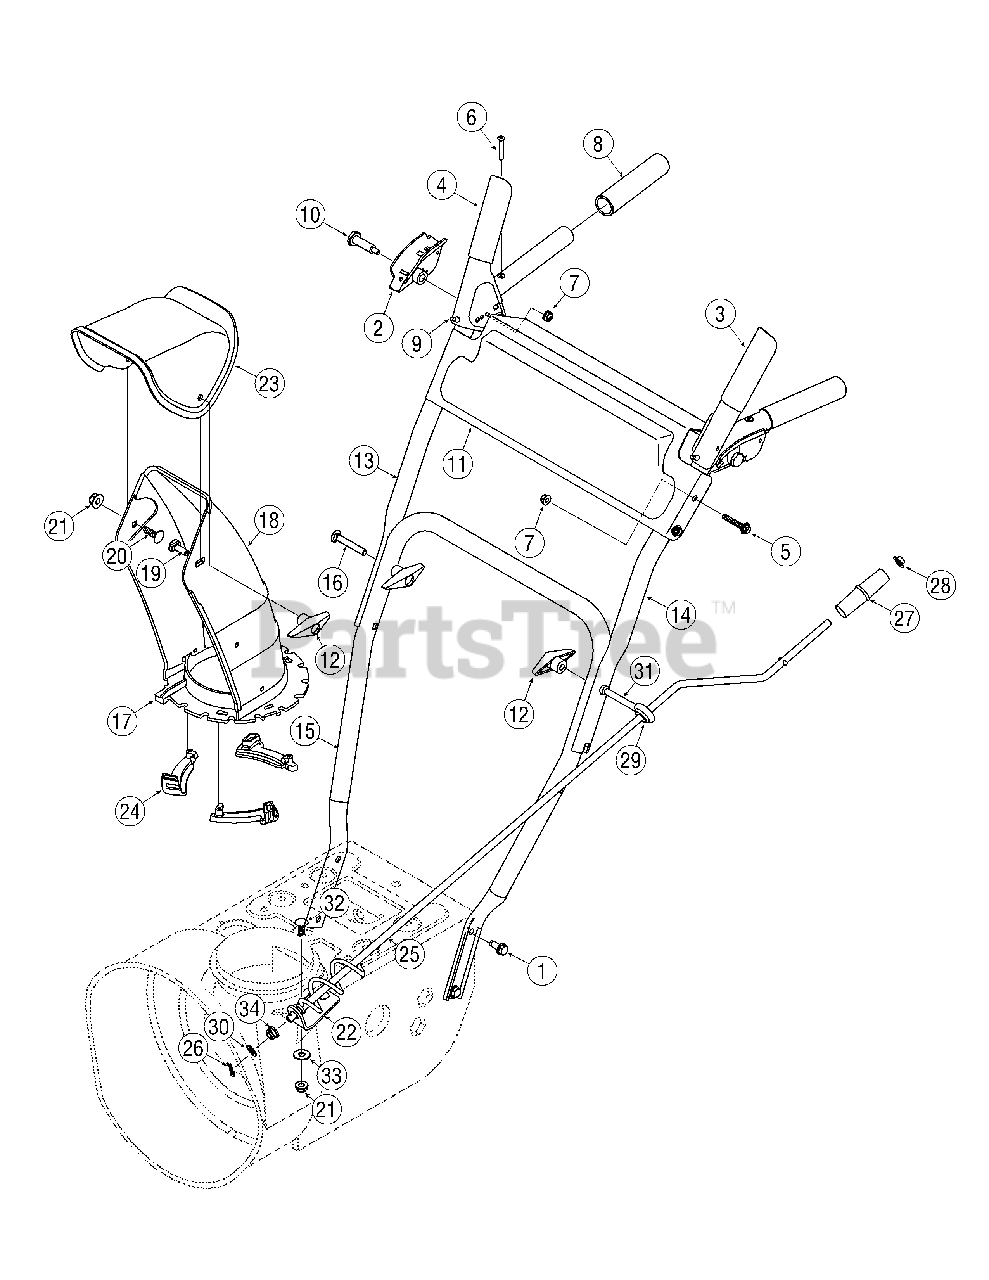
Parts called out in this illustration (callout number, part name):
1	Screw, 5/16-18 x .750
2	Clutch Lock Handle Assembly, LH
2	Clutch Lock Handle Assembly, RH
3	Engagement Assembly, LH
4	Engagement Assembly, RH
5	Hex Head Screw, 1/4-20 x 1.50
6	Machine Screw, #10-24 x 1.375
7	Flange Lock Nut, 1/4-20
8	Grip, 1.0 ID x 5.0 LG
9	Rubber Bumper, .62 OD x .22 Thick
10	Shoulder Screw, .437 x 1.345 x 1/4-20
11	Handle Panel
12	Wing Knob
13	Upper RH Handle
14	Upper LH Handle
15	Lower Handle
16	Carriage Screw, 5/16-18 x 2.25
17	Lower Chute Assembly
18	Lower Chute
19	Carriage Bolt, 5/16-18 x 1.00
20	Carriage Bolt, 5/16-18 x .750
21	Flange Lock Nut, 5/16-18
22	Chute Crank Bracket
23	Upper Chute
24	Flange Keeper
25	Chute Crank
26	Cotter Pin, .072 x 1.13
27	Crank Knob
28	Push Cap, 3/8
29	Rubber Grommet
30	Flat Washer, .375 x .738 x .063
31	Eye Bolt
32	Carriage Screw, 5/16-18 x 1.00
33	Flat Washer, .349 x .879 x .063
34	Plastic Bushing, .380 ID
